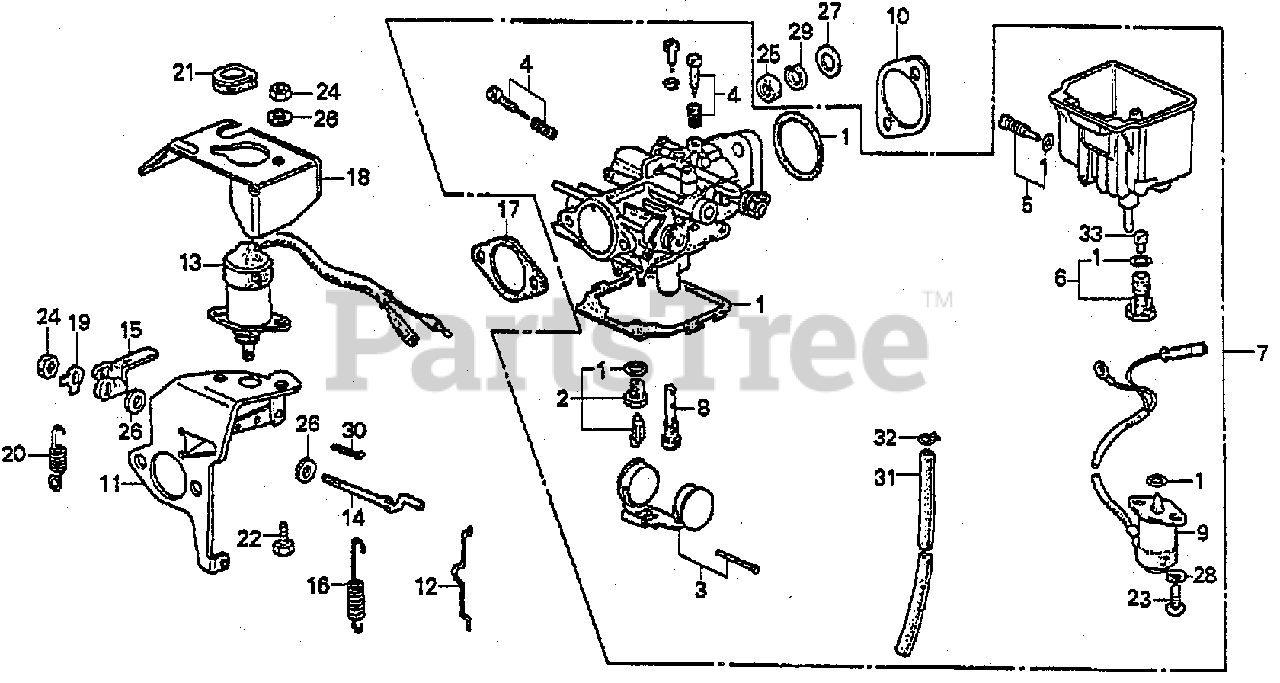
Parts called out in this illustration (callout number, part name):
1	GASKET SET
2	VALVE SET, FLOAT
4	SCREW SET A (NOT AVAILABLE)
5	SCREW SET, DRAIN
6	SCREW SET B (NOT AVAILABLE)
7	CARBURETOR ASSY.
7	CARBURETOR ASSY. (NOT AVAILABLE)
8	NOZZLE, MAIN (NOT AVAILABLE)
9	VALVE ASSY., SOLENOID (NOT AVAILABLE)
10	SHIM, CARBURETOR (NOT AVAILABLE)
11	STAY, SOLENOID (NOT AVAILABLE)
12	ROD, CHOKE (NOT AVAILABLE)
13	CHOKE, SOLENOID (NOT AVAILABLE)
14	ROD, MANUAL CHOKE
15	LEVER, CHOKE
16	SPRING, CHOKE RETURN (NOT AVAILABLE)
17	GASKET, AIR CLEANER (NOT AVAILABLE)
18	COVER, SOLENOID (NOT AVAILABLE)
19	WASHER, LOCK
20	SPRING, CHOKE (NOT AVAILABLE)
21	GROMMET, TUBE (NOT AVAILABLE)
22	BOLT, HEX. (5X12)
23	SCREW, PAN (5X10)
24	NUT, HEX. (5MM)
25	NUT, HEX. (6MM)
26	WASHER, PLAIN (5MM)
27	WASHER, PLAIN (6MM)
28	WASHER, SPRING (5MM)
29	WASHER, SPRING (6MM)
30	PIN, SPLIT (2.0X15)
31	BULK HOSE, FUEL (3.5X3000) (3.5X270)
32	CLIP, TUBE (B7)
33	JET, MAIN (#92)
